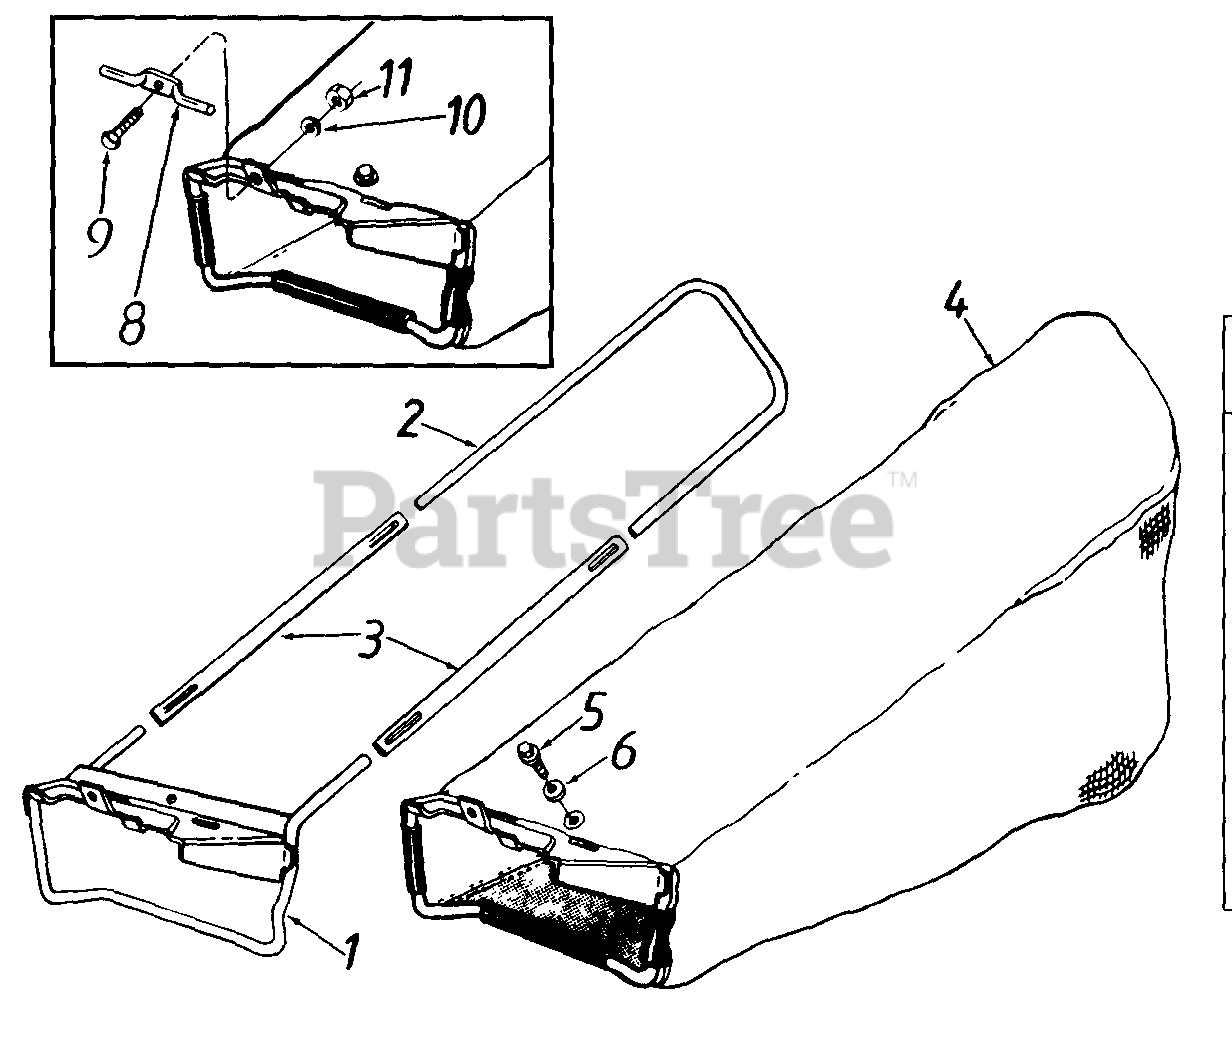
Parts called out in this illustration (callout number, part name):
4	Grass Bag
5	Hex Wash Hd. TT-Tap Scr. 1/4-20 x 5" Lg
6	Bell-Wash 1/4" I.D.
8	Grass Bag Hook
9	Hex Bolt 1/4-20 x .62" Lg
10	L-Wash 1/4" I D.
11	Hex Nut 1/4-20 Thd
